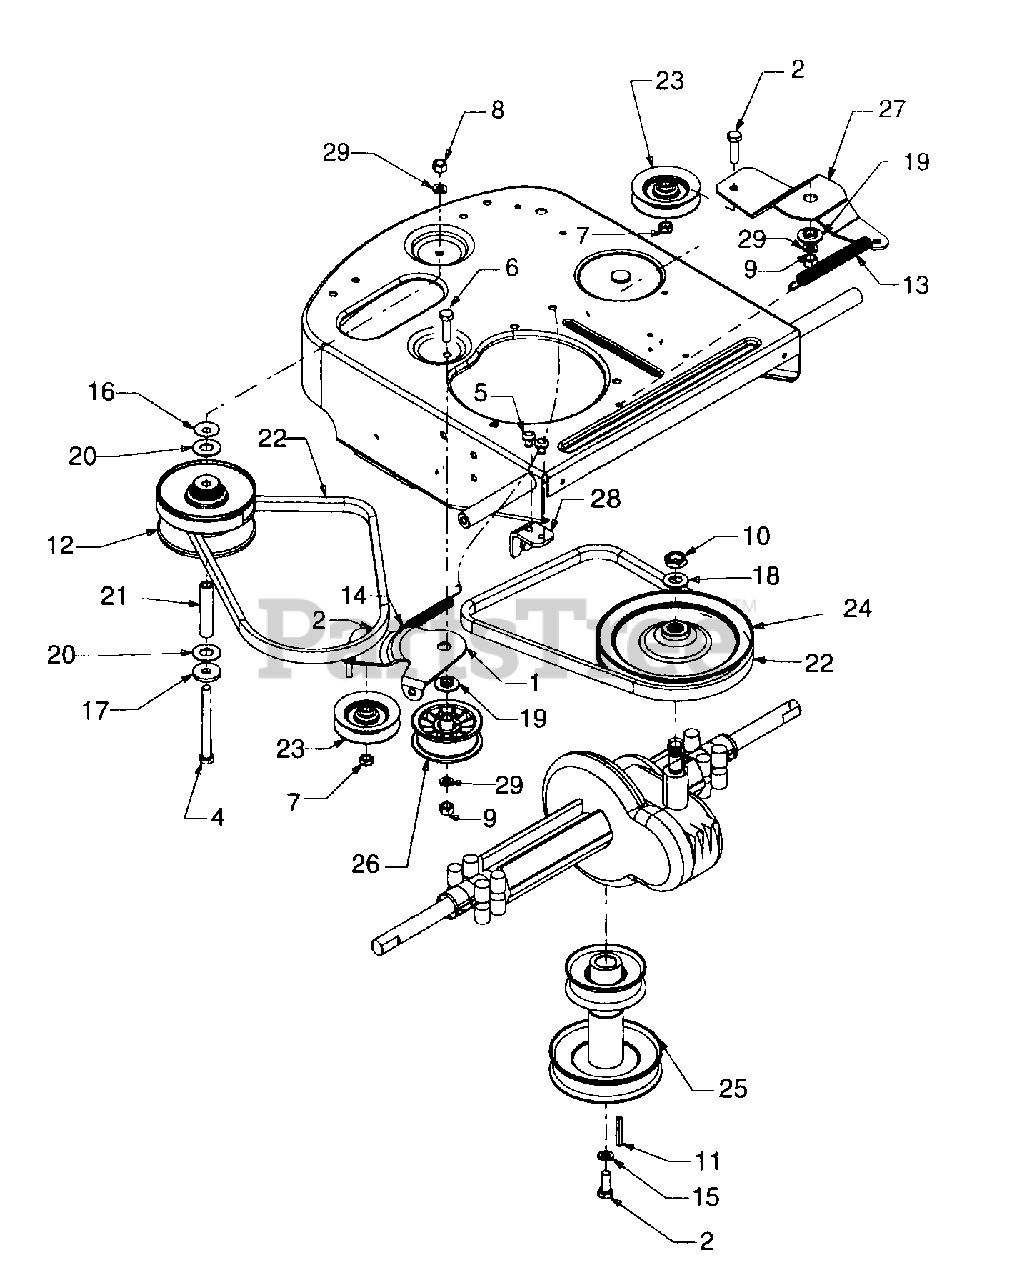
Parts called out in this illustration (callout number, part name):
1	Idler Bracket Assembly
2	Hex Screw 7/16-20 x 1.00
4	Cap Screw 3/8-24 x 3.75
5	Pan Head TL Screw 5/16-18 x .75
6	Hex Screw 3/8-16 x 2.0 Special
7	Jam Lock Nut 3/8-24
8	Hex Nut 3/8-24
9	Hex Nut 3/8-16
10	Hex Jam Nut 9/16-18 (Gr. 5)
11	Square Key
12	Variable Speed Pulley Assembly
13	Extension Spring
14	Extension Spring
15	Lock Washer 7/16 I.D.
16	Bell Washer .406 I.D. x 1.13 O.D.
17	Flat Washer 3/8 x 1.25 O.D.
18	Belleville Washer .567 x 1.125 x .06
19	Shoulder Spacer
20	Bearing
22	V-Belt
23	Idler Pulley
24	Transmission Pulley
25	Engine Pulley
26	Flat Idler Pulley
27	Idler Bracket
28	Cable Bracket
29	Lock Washer 3/8 I.D.
